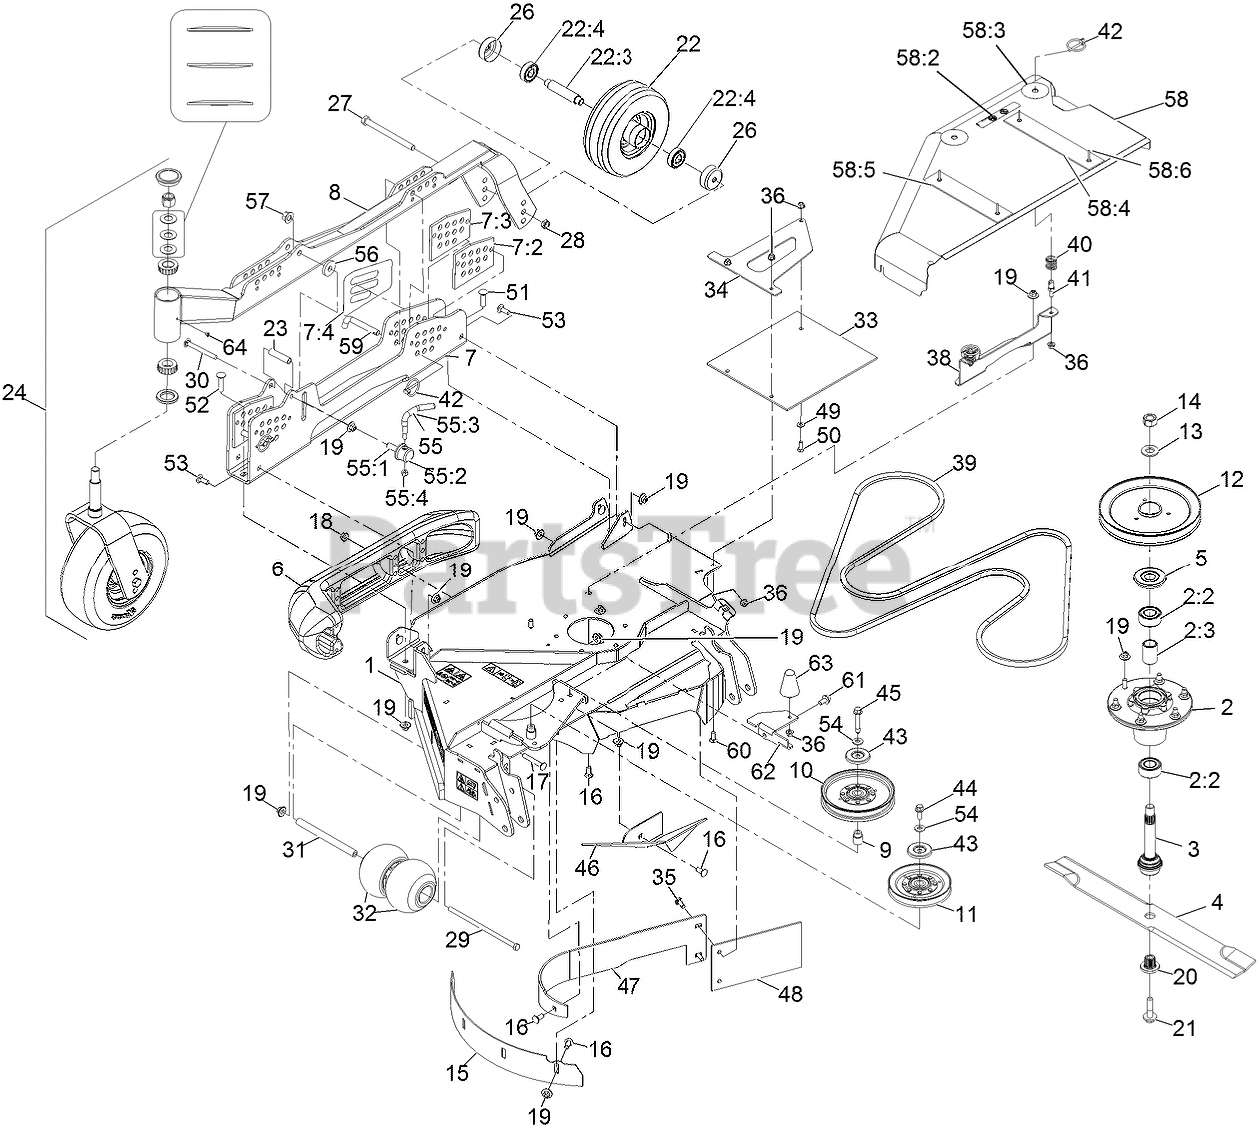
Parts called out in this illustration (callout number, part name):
1	ASM-Deck, RH Wing 96
2	ASM-Cutter Hsg
2:2	Bearing-3205 Trashguard
2:3	Spacer-Bearing
3	ASM-SPINDLE AND SEAL
5	GUARD-BEARING, TOP
6	SKID-BUMPER, DECK
7	RH HOC CHANNEL ASM
7:2	PLATE-GUIDE, HOC (LH)
7:3	PLATE-GUIDE, HOC (RH)
7:4	DECAL-HEIGHT OF CUT, RH
8	CALL CUSTOMER SERVICE
9	BUSHING-IDLER
10	IDLER-PULLEY
11	IDLER-V
12	SHEAVE-SINGLE 96RD
14	NUT-HEX
15	BAFFLE-DEPTH, RH
16	BOLT-CARR
17	SCREW-CARR
18	NUT-HF, NI
19	Nut-Nyloc 3/8-16 Flg
20	BUSHING,SPLINED
21	SCREW,SEMS 1/2-20 X 2.19
22	WHEEL AND TIRE ASM
22:3	AXLE-CASTER
22:4	BEARING
26	Guard-Seal
27	SCREW-HH
28	NUT-HEX
29	SCREW-HH
30	SCREW-CARR
31	SPACER-WHEEL
32	ROLLER-SCALP, ANTI
33	GUARD-TIRE
34	SUPPORT-FLAP, RH
35	SCREW-CARR
36	NUT-HF, NI
38	BRACKET-SHIELD MOUNT, OUT
41	PIN-SPRING
42	PIN-LYNCH
43	SHIELD-DUST
44	SCREW-HHF 3/8-16 X 1
45	SCREW-HHF W/ PATCH
46	BAFFLE-DEFLECT, RH
47	BAFFLE-DOGLEG, RH
48	FLAP-RUBBER
49	WASHER-PLAIN
50	SCREW-HH
51	SCREW-CARR
52	SCREW-CARR
53	BOLT-CARR
54	WASHER-BELLEVILLE
55	LEVER ASM
55:1	SCREW-LOCK
55:2	CAP-LOCK
55:4	NUT-LOCK, NI
57	Nut-Lock 1/2-13
58	ASM-Wing Shield RH
58:2	DECAL-NO STEP
58:3	DECAL-SCRATCH COVER
58:4	Plate-Uhmw 2"
58:5	Plate-Uhmw 2" Rf
58:6	Rivet-Pop
59	PIN-HOC
60	BOLT-CARR
61	SCREW-HWH
62	BRACKET-COVER RETAINER
63	BUMPER-RUBBER
